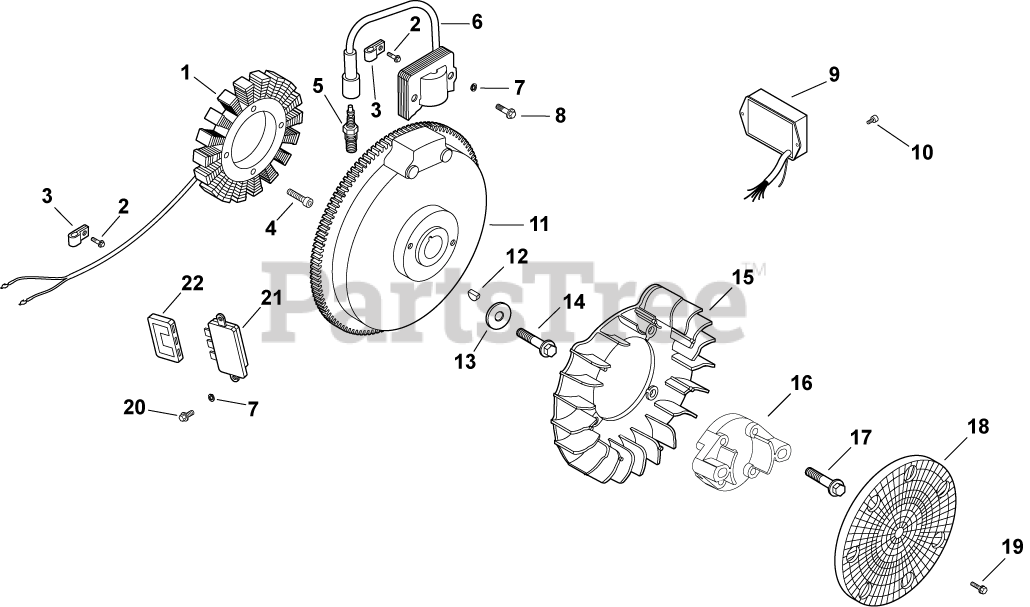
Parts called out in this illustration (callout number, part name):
1	KIT, 15 / 20 AMP STATOR
2	SCREW, FLG THD FRM M5X.8X10
4	SCREW, M5X0.8X25 - (#25086402S)
5	PLUG, SPARK (STD)
6	MODULE, IGNITION
7	WASHER, INT TOOTH LOCK 1/4"
8	SCREW, SCKT THRD FRMM5X0.8X20 - DISCONTINUED
9	MODULE, DIGITAL SPD ADV-USE 12 707 01-S
10	SCREW, PHL THD FRM M4.2X13
11	FLYWHEEL - DISCONTINUED
12	KEY, 3/16" X 5/8"
13	WASHER, FLAT 13/32"
14	SCREW, FLG M10X1.5X45 - (#25086361S)
15	FAN - DISCONTINUED
16	ADAPTER, DRIVE SHAFT
17	SCREW, FLG M8X1.25X45
18	SCREEN, GRASS
19	BOLT, SHOULDER
20	SCREW, WSH HD TAP #8-18X1"-DISC.
21	REG/RECT-15 AMP (KM)-USE 41 403 10-S
22	CONNECTOR, BODY (KM)-USE 25 155 41-S
